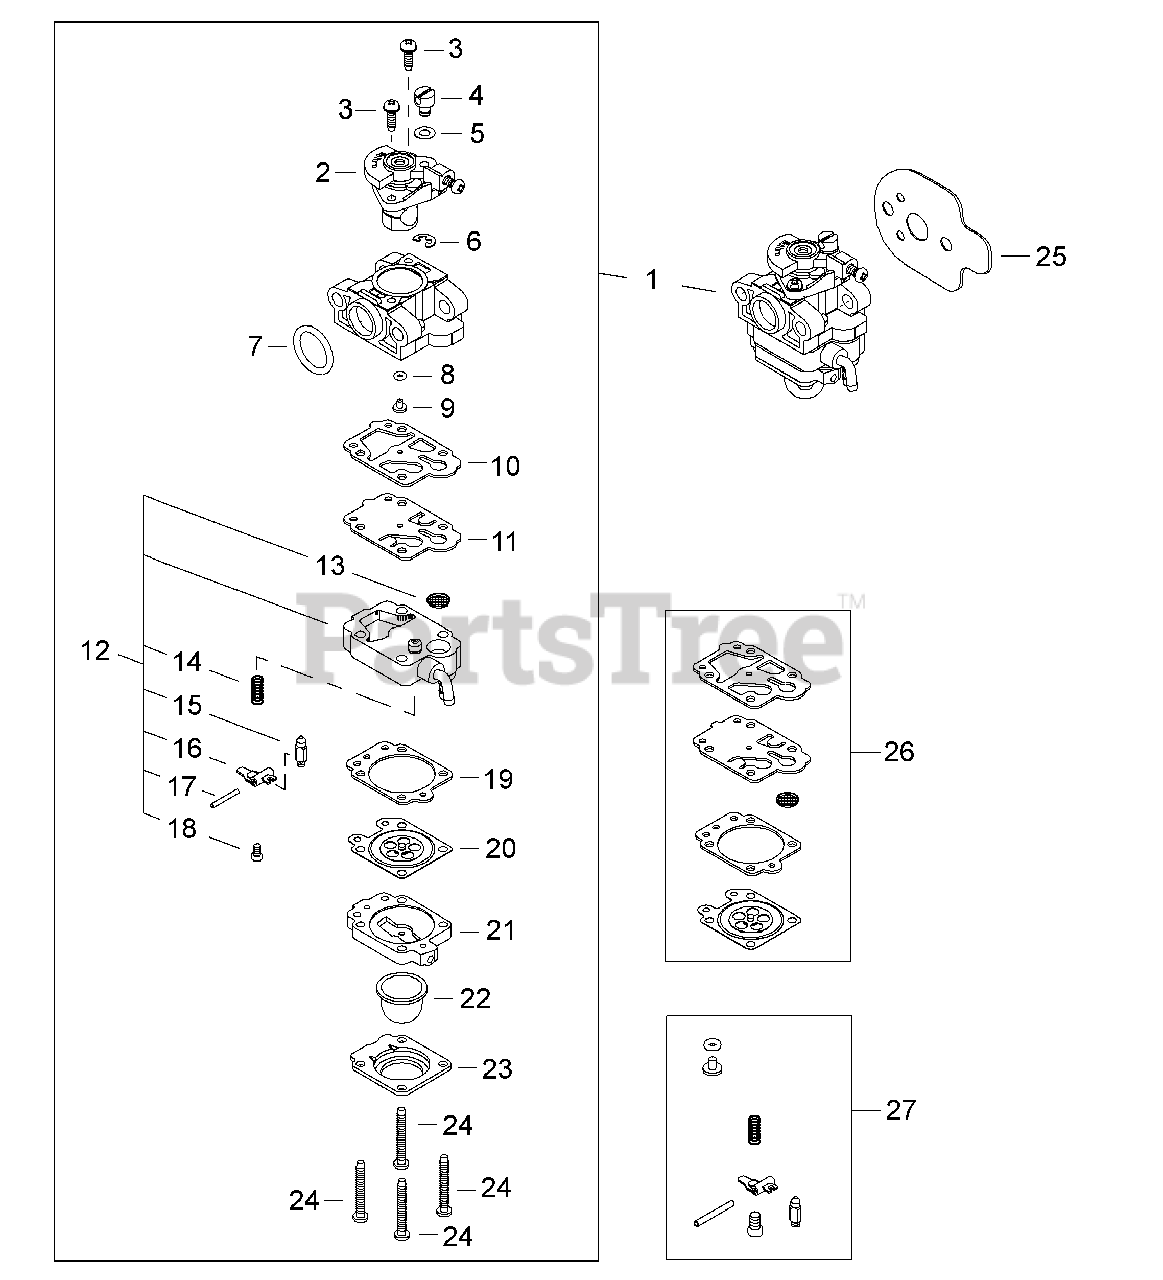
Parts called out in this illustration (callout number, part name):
1	CARBURETOR
2	THROTTLE VALVE ASSY
3	SCREW
4	SWIVEL
5	WASHER
6	RING, RETAINING
7	O-RING - 15
8	O-RING
9	JET, MAIN
10	GASKET, PUMP
11	DIAPHRAGM, PUMP
12	PUMP BODY ASSY
13	STRAINER
14	SPRING, METERING LEVER
15	VALVE, INLET NEEDLE
16	LEVER, METERING
17	PIN, METERING LEVER
18	SCREW, METERING LEVER PIN
19	GASKET, METERING
20	DIAPHRAGM, METERING
21	BASE, PURGE
22	BULB, PURGE
23	RETAINER, PURGE BULB
24	SCREW, PUMP COVER
25	GASKET
26	DIAPHRAGM/GASKET KIT
27	INLET NEEDLE VALVE KIT
